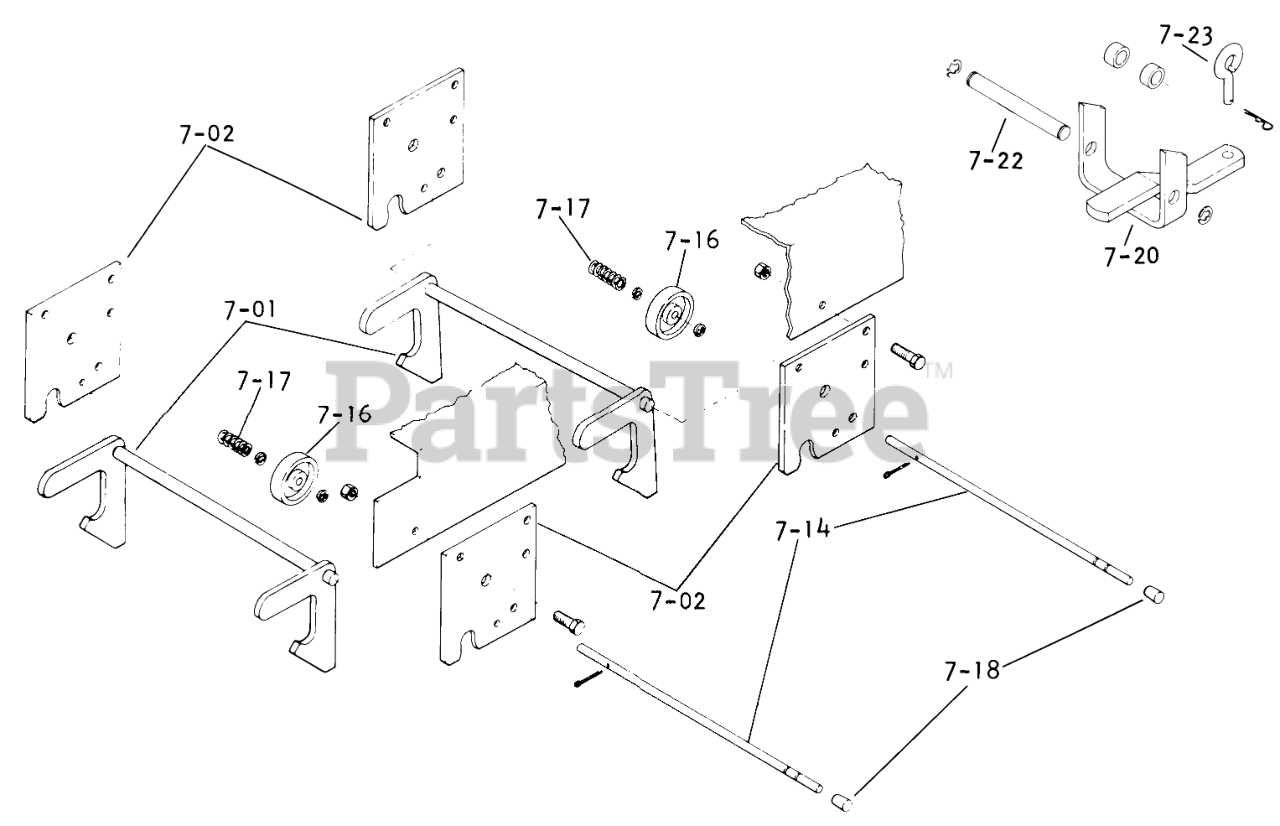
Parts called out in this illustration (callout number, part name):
7-01	Assy-Latch
7-02	Hitch Plate
7-14	Rod Lock
7-17	SPRING-COMPRESSION
7-18	CAP-ROD, PLUNGER
7-20	Hitch
7-22	PIN-STATIONARY HITCH
7-23	Pin-Tool
